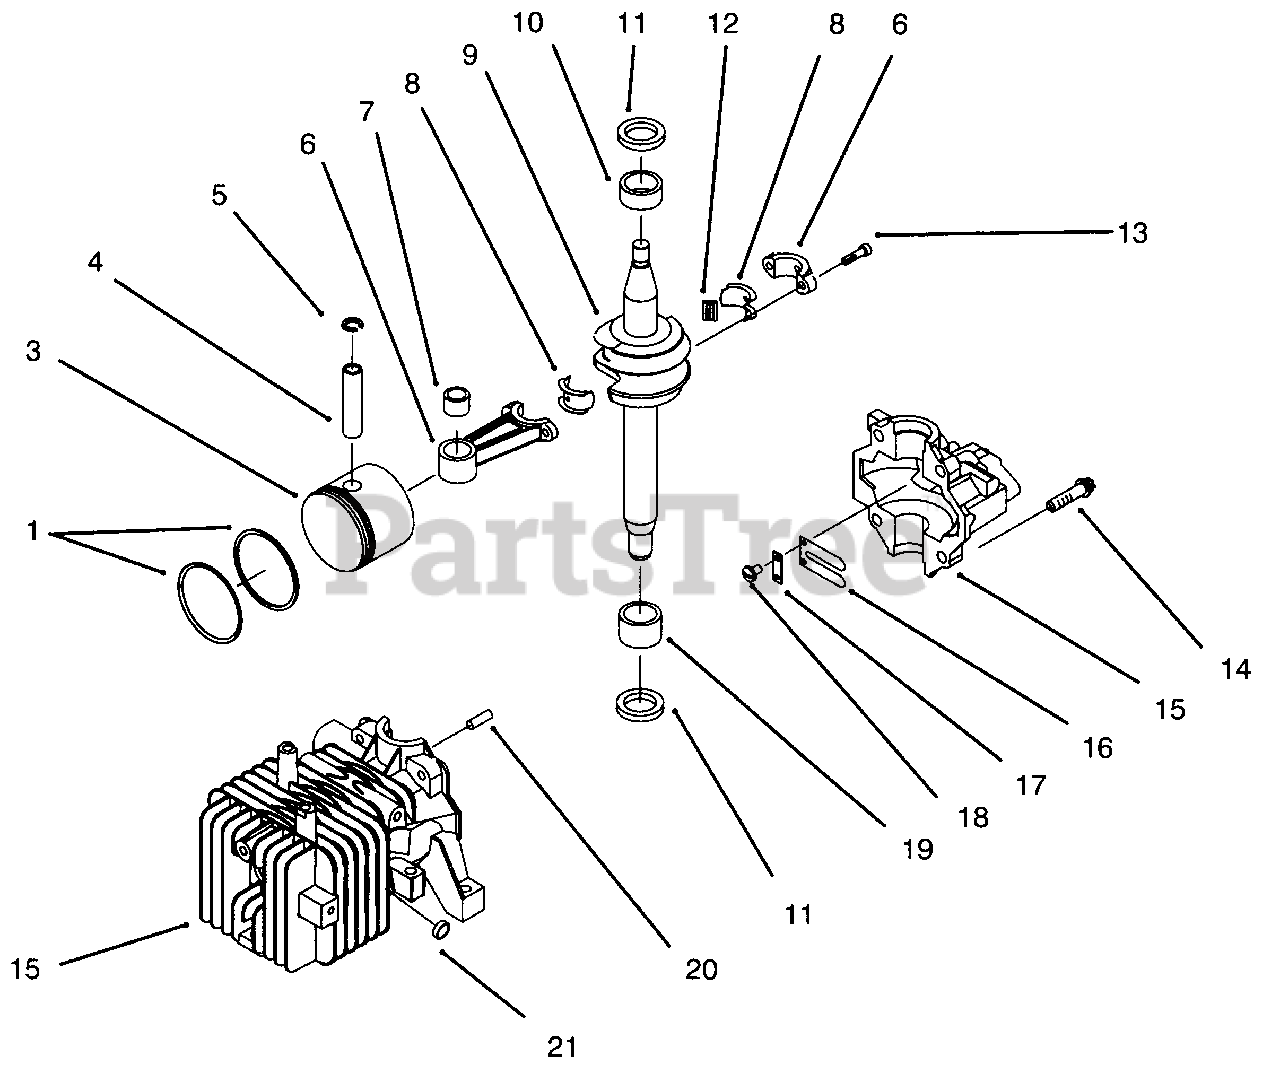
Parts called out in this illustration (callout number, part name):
1	Set-Rings, Piston
3	Piston & Ring Set
4	Pin-Wrist
5	Ring-Retaining
6	Connecting Rod Assembly (Incl. Ref. #8, 12 & 13)
8	Liner-Split (Set of 2)
9	Crankshaft
10	Bearing-Upper Main
11	Seal-Oil
12	Bearing-Needle
13	Screw-Hex. Hd. Cap
14	Screw-Hex. Washer Hd.
15	Cylinder & Crankcase Cover (Incl. Ref. #14, 16, 17, 18, 20, & 21)
16	Reed-Carburetor
17	Reed-Backup Plate
19	Bearing-Needle
21	Plug-Core
